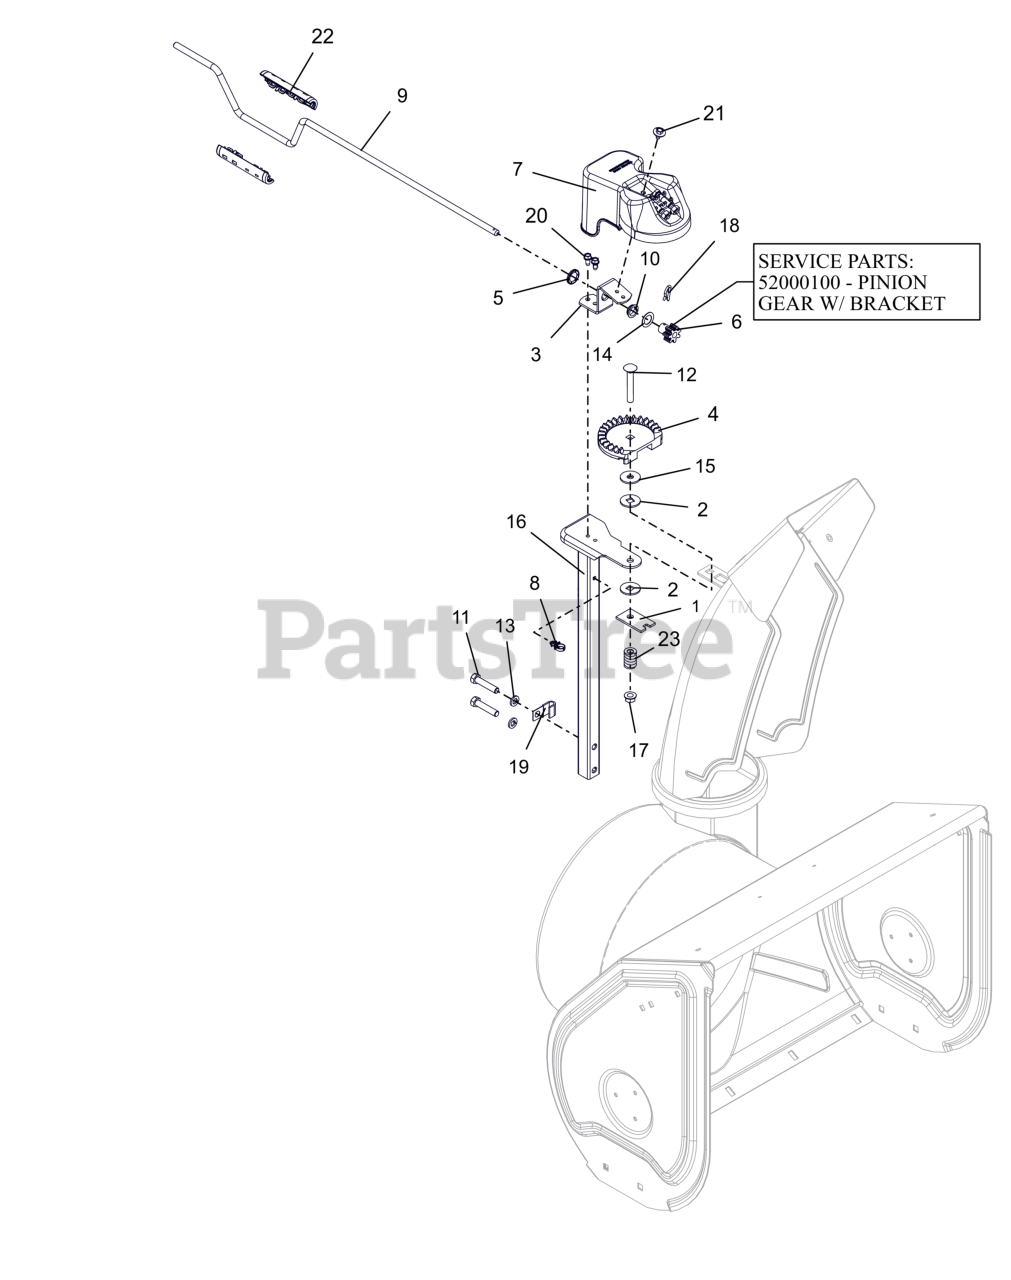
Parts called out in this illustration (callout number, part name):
1	PLATE, FRICTION
2	FRICTION WASHER
3	BRACKET, PINION GEAR
4	CHUTE GEAR
5	PUSHNUT .625
6	PINION GEAR - CHUTE
6	PINION GEAR W/BRACKET
7	GEAR COVER ASSY LG SHEAR BOLT
8	CLIP, CABLE GUIDE
9	ROD,CRANK - SMDASH DLX
10	BUSHING, POLYLINER-.63 SNAPIN
11	BLT, HEX .38-16X1.75 G5 ZCC
12	BLT,RHSN .38-16X2.50 G5 ZCC
13	WSHR,LK-REG .375X.094 ZCC
14	WSHR-THRST .625 X 1.0 X .03
15	WSHR FL STL .406X1.25X.10ZC120
16	PEDESTAL, CHUTE - CRANK
17	NUT-LK-TOP-FLG .38-16 ZC120
18	PIN, SPRING CLIP
19	J-CLAMP
20	SCR-TAP .25-20X.50 HWH ZCC
21	SCR, TAP .25-20X.50 LG HWH ZCC
22	KNOB,CHUTE CRANK-DELUXE
23	SG-COMP .187X.56X1.62
